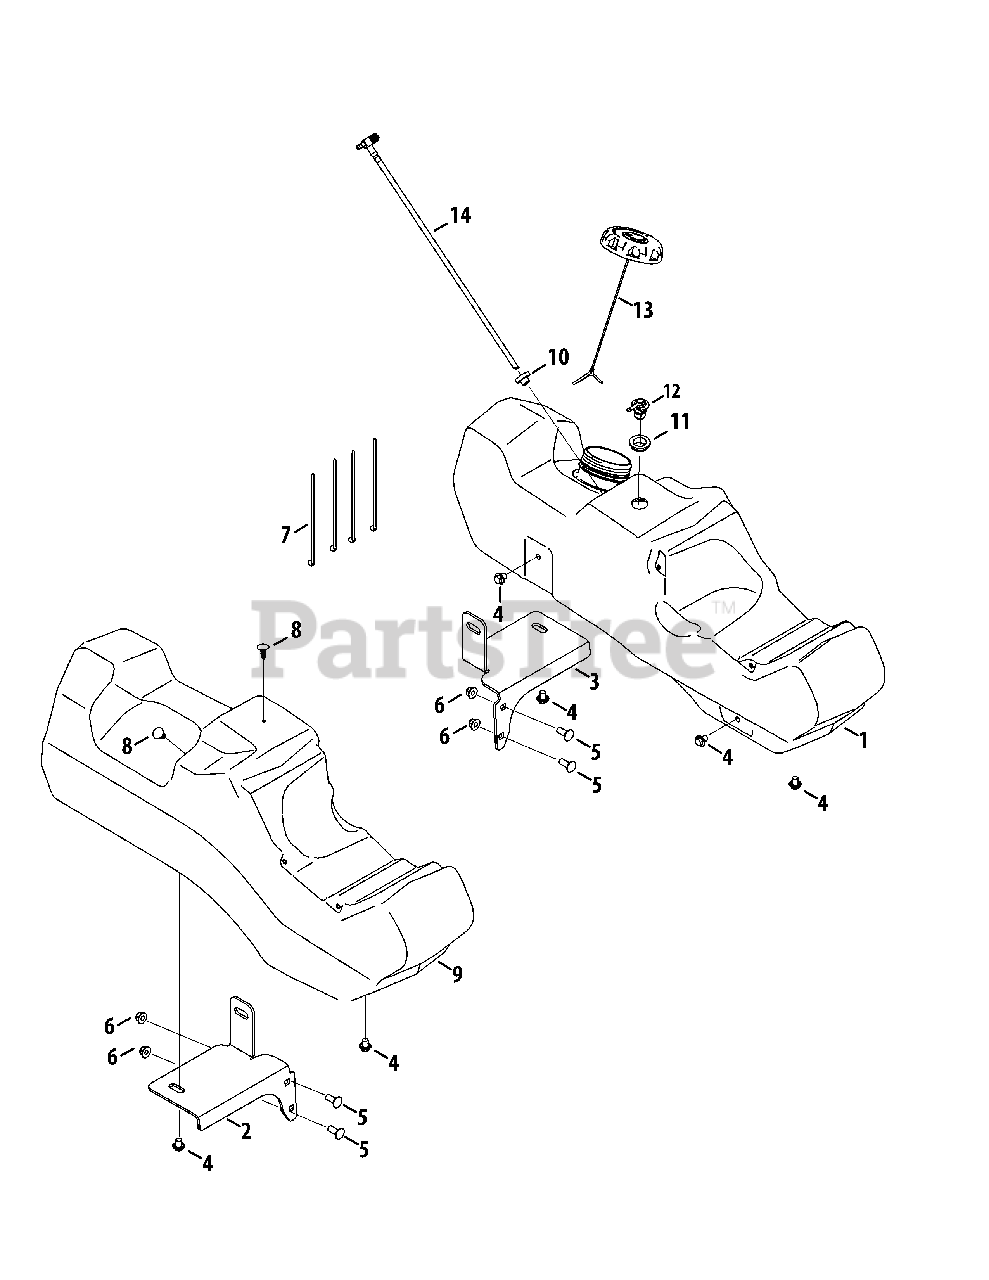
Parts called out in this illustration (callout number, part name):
1	Fuel Tank Assembly, LH
2	Rear Fuel Bracket, RH
3	Rear Fuel Bracket, LH
4	Hex Cap Screw, 3/8-16 x .500
5	Carriage Bolt, 3/8-16 x .500
6	Nut, 3/8-16, Flangelock
7	Cable Tie
8	Clip, .250 Dia.
9	Console, RH
10	Fuel Tank Grommet
11	Grommet, .755 x .955 x .55
12	Fuel Rollover Valve
14	Fuel Pickup Valve
